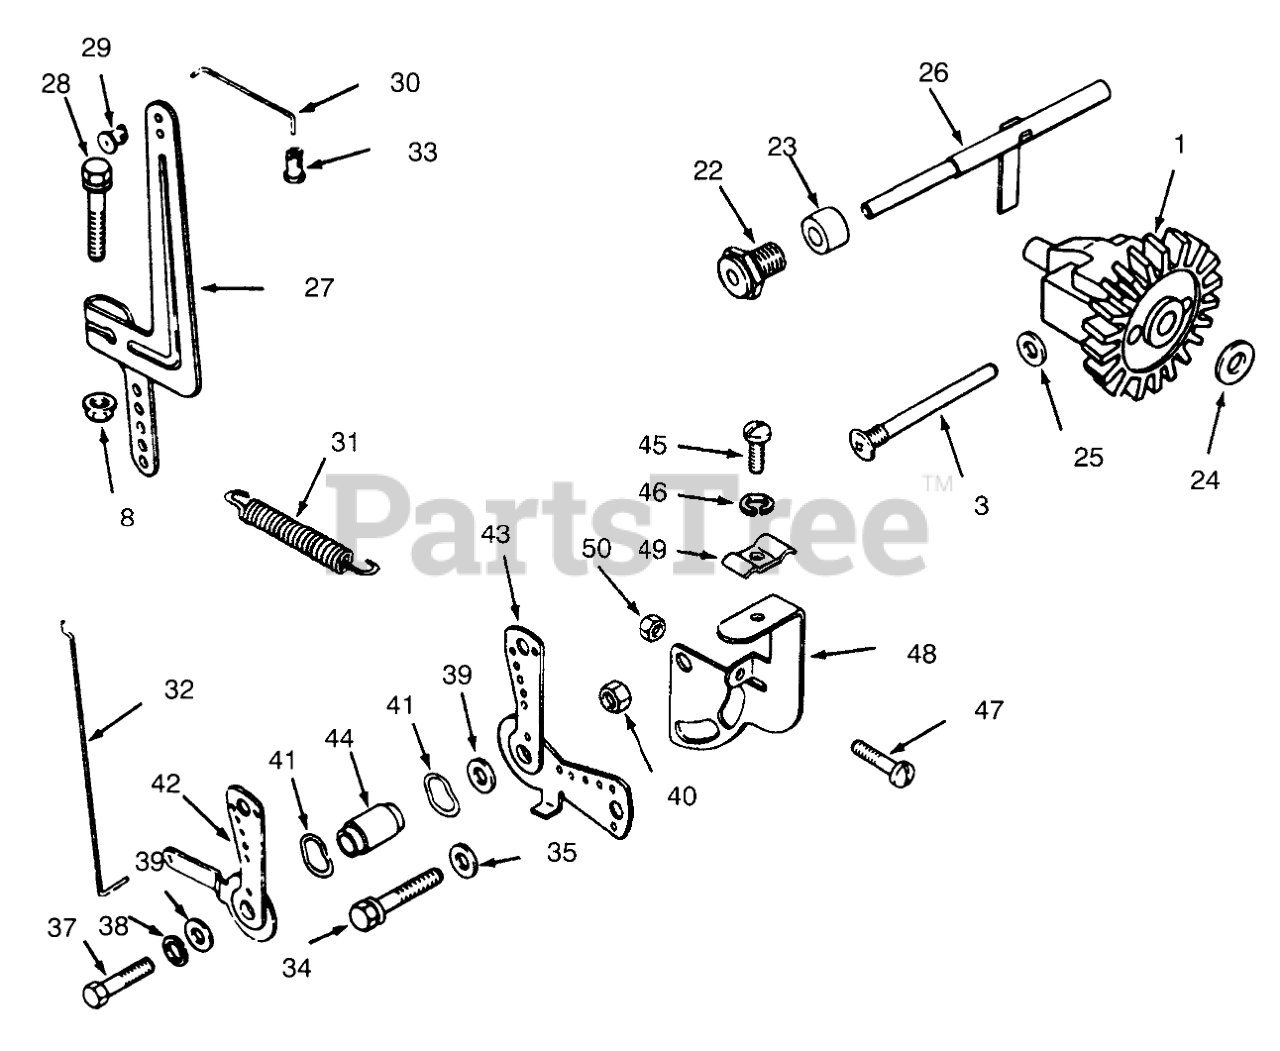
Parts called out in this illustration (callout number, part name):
1	Kit-Governor Gear(Includes 24)
3	Govenor Stop Pin
8	Palnut
22	Bushing
23	Spacer
24	Washer
25	Washer
26	Governor Cross Shaft Kit
27	Governor Lever
28	Screw
29	Bushing
30	Carburetor Linkage
31	Spring (Governor to Cab.)
32	Choke Linkage (Carb. to Choke Shaft)
33	Bushing
34	Screw
35	Washer
37	Screw
38	Washer-Lock
39	Washer
41	Washer
42	Choke Control Lever
43	Lever-Throttle Control
44	Space
45	Screw
46	Washer
47	Screw
48	Bracket-Clutch Control
49	Clamp
